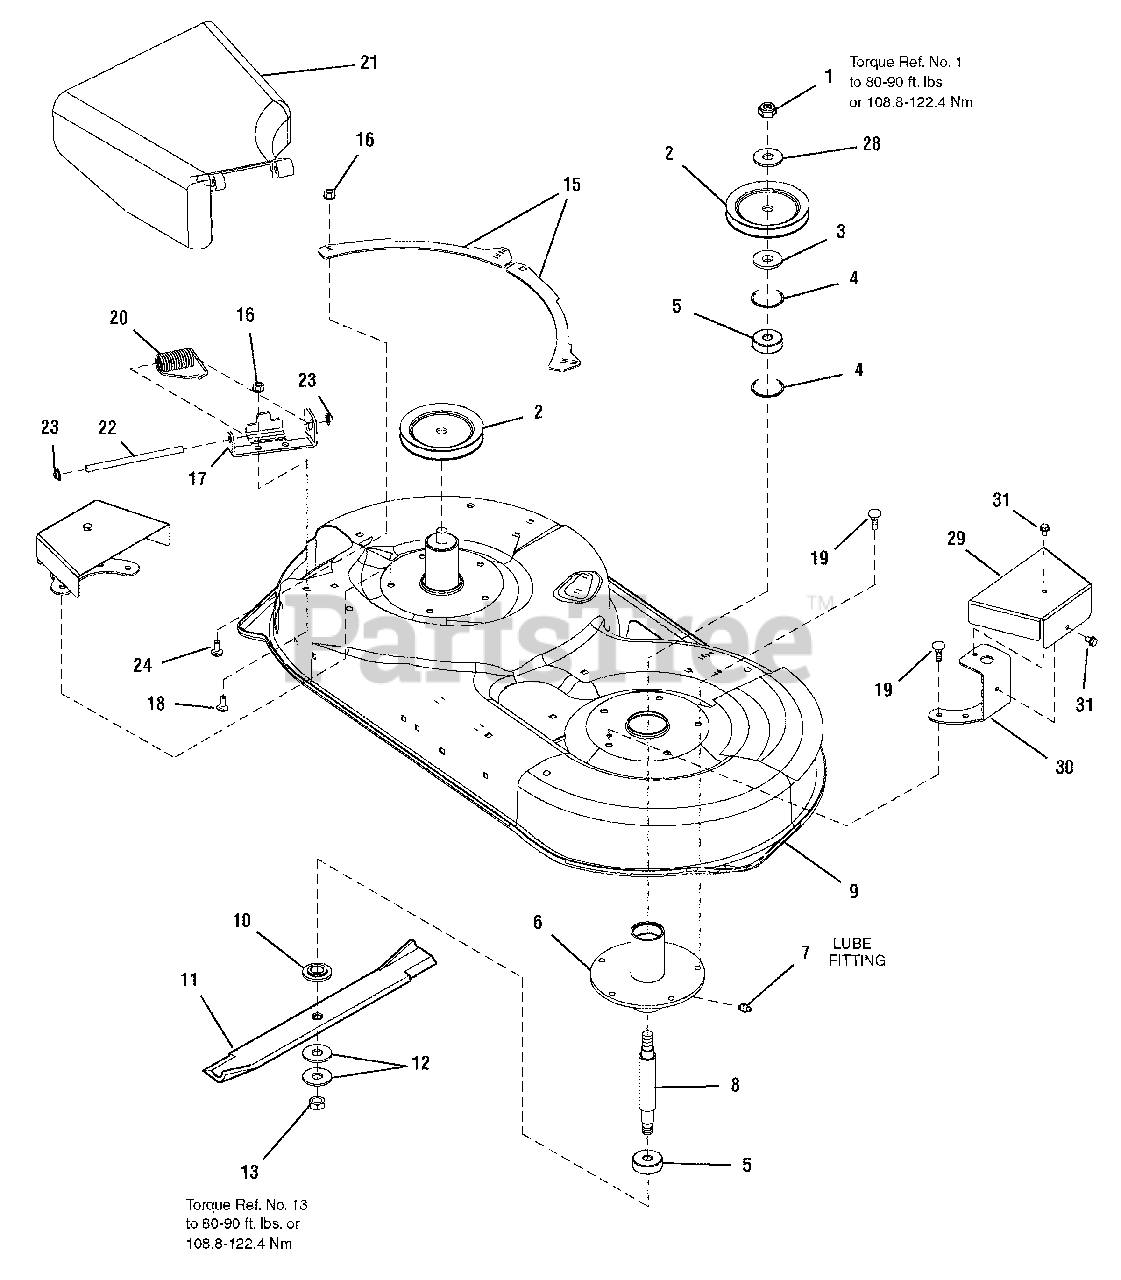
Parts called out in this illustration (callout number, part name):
1	NUT, Hex Nylock, 5/8
2	PULLEY, Drive
3	SPACER, Pulley
4	RING, Retaining
5	BEARING, Spindle
6	TUBE & PLATE ASSEMBLY, Spindle
7	LUBE, Fitting
8	SHAFT, Spindle
9	HOUSING, 42"
10	WASHER, Spindle Blade
11	BLADE
12	WASHER, Belleville
13	NUT, Hex, 9/16
16	NUT, ESNA, 5/16
17	BRACKET, Hinge
18	BOLT, Carriage, 5/16-18 x 3/4
19	SCREW, Taptite, 3/8-16 x 3/4
20	SPRING, Torsion
22	ROD, Deflector
23	PUSHNUT
24	CAPSCREW, 5/16-18 x 1
28	LOCKWASHER, Internal Tooth, 5/8
29	COVER, Pulley
30	SUPPORT, Pulley Cover
31	SCREW, Taptite, 5/16 - 18 x 1/2
